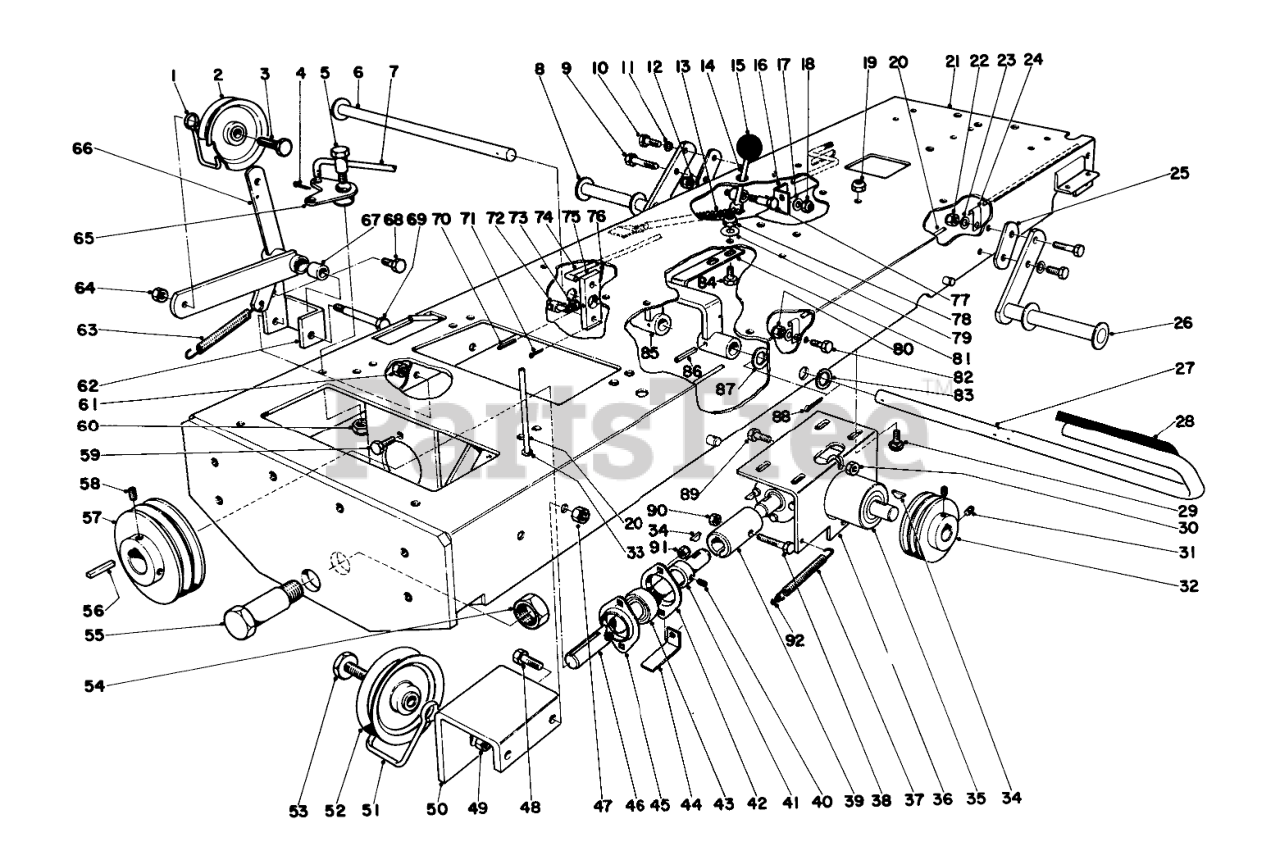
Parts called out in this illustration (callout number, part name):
1	Belt Retainer
2	IDLER PULLEY
3	Leveler Head Bolt
4	PIN-COTTER
6	Brake Shaft
7	Idler Rod
8	Bracket Foot Rest
9	SCREW-HH
10	SCREW-HH
11	WASHER-LOCK
12	Nut
13	IDLER ARM SPRING
14	Brake Lock
15	Knob
16	Brake Rod Retainer
17	WASHER-FLAT
19	Nut
20	Gas Line
21	Chassis 950
23	WASHER-FLAT
25	Spacer Foot Rest
26	Bracket Foot Rest
27	Brake Crank Arm
28	PAD-BRAKE
29	BOLT-CARR
31	SCREW-SET
32	Pulley Drive
33	Nyliner
34	KEY-WOODRUFF
35	Gear Box
36	Bracket Right Angle Gear Box
37	Spring
38	SCREW-HH
39	Coupling
40	SCREW-SET, HSH
41	Collar
42	Bearing Flange
43	Bearing
44	Belt Guide
45	Bearing Incl. Ref. 41-43
46	Drive Shaft
47	Nut
48	SCREW-HH
50	Idler Bracket
51	Belt Retainer
52	IDLER PULLEY
53	Leveler Head Bolt
55	Pivot Bolt
57	Pulley Drive
58	SCREW-SET, HSH
59	SCREW-HH
60	NUT-JAM
62	Mounting Bracket Idler
63	Spring
65	Bell Crank
66	Idler Arm Incl. Ref. No. 67
67	Bushing
68	SCREW-HH
69	Shoulder Bolt
70	Roll Pin
71	PIN-COTTER
72	Pivot Clutch Rod
74	Brake Rod
75	Bracket Idler
76	=SCRE-HH
78	Nut
79	WASHER-FLAT
80	Nut
81	Stop Brake Pedal
82	SCREW-HH
83	Washer
84	SCREW-HH
85	Bracket Assy.
86	Roll Pin
87	Washer
88	PIN-COTTER
89	SCREW-HH
90	NUT-LOCK, CONE
91	Nut
92	S-Hook
